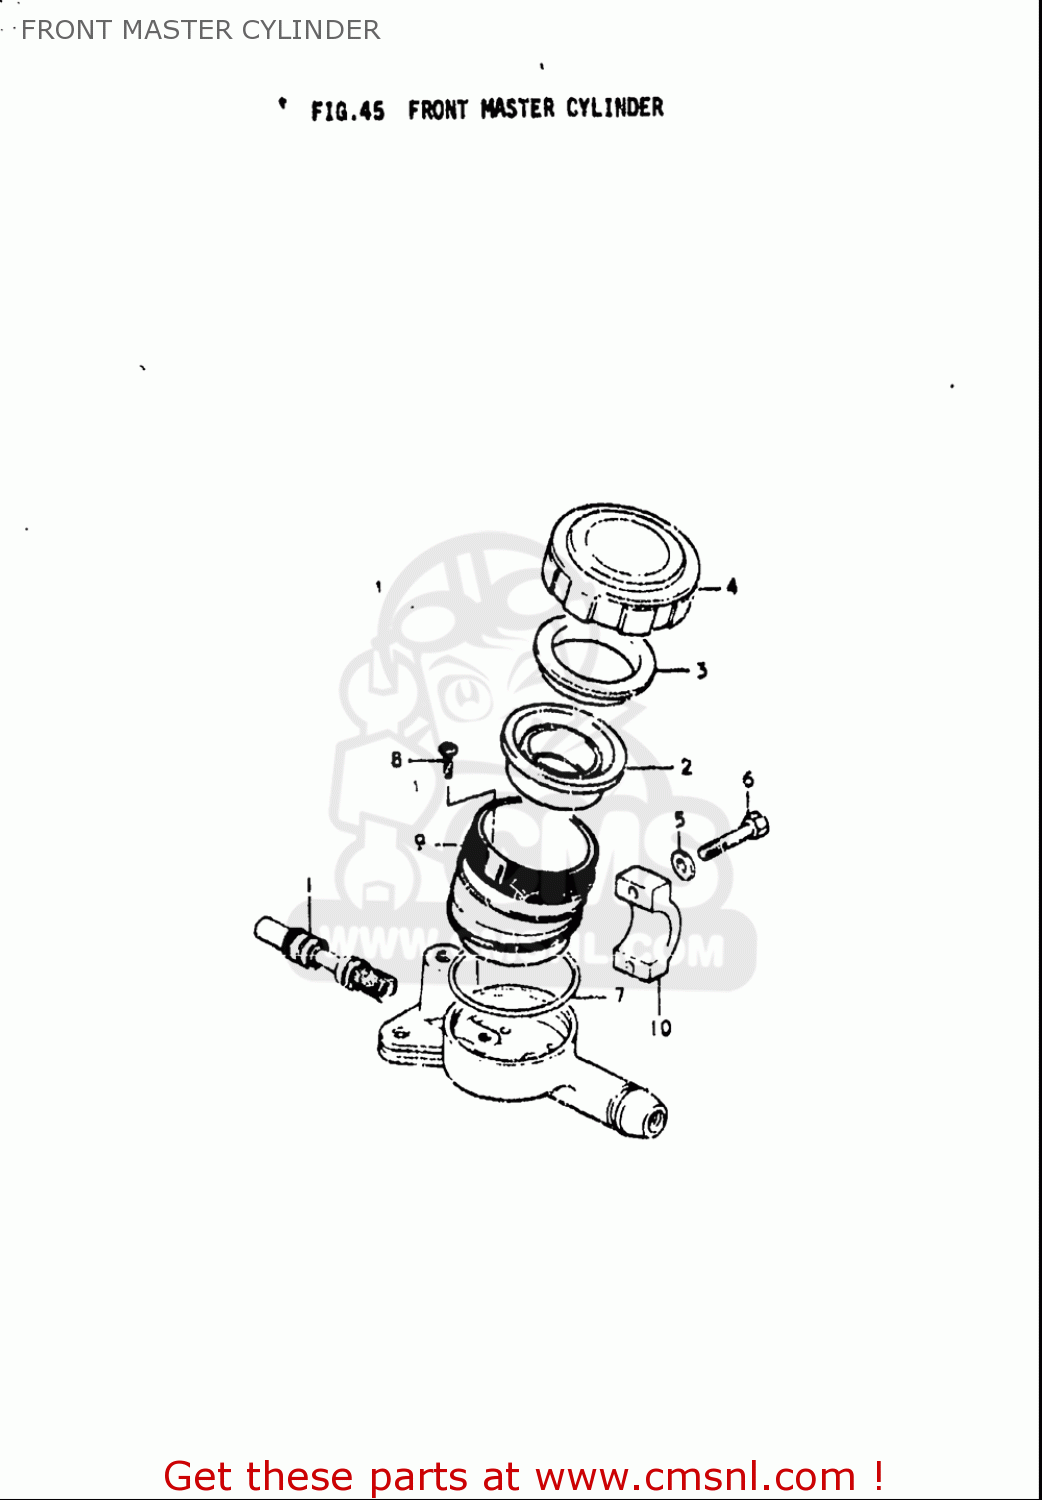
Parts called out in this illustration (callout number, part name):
1	PISTON & CUP SET
2	DIAPHRAGM
3	PLATE,DIAPHRAGM
5	WASHER
6	BOLT
7	O RING
9	RESERVOIR
